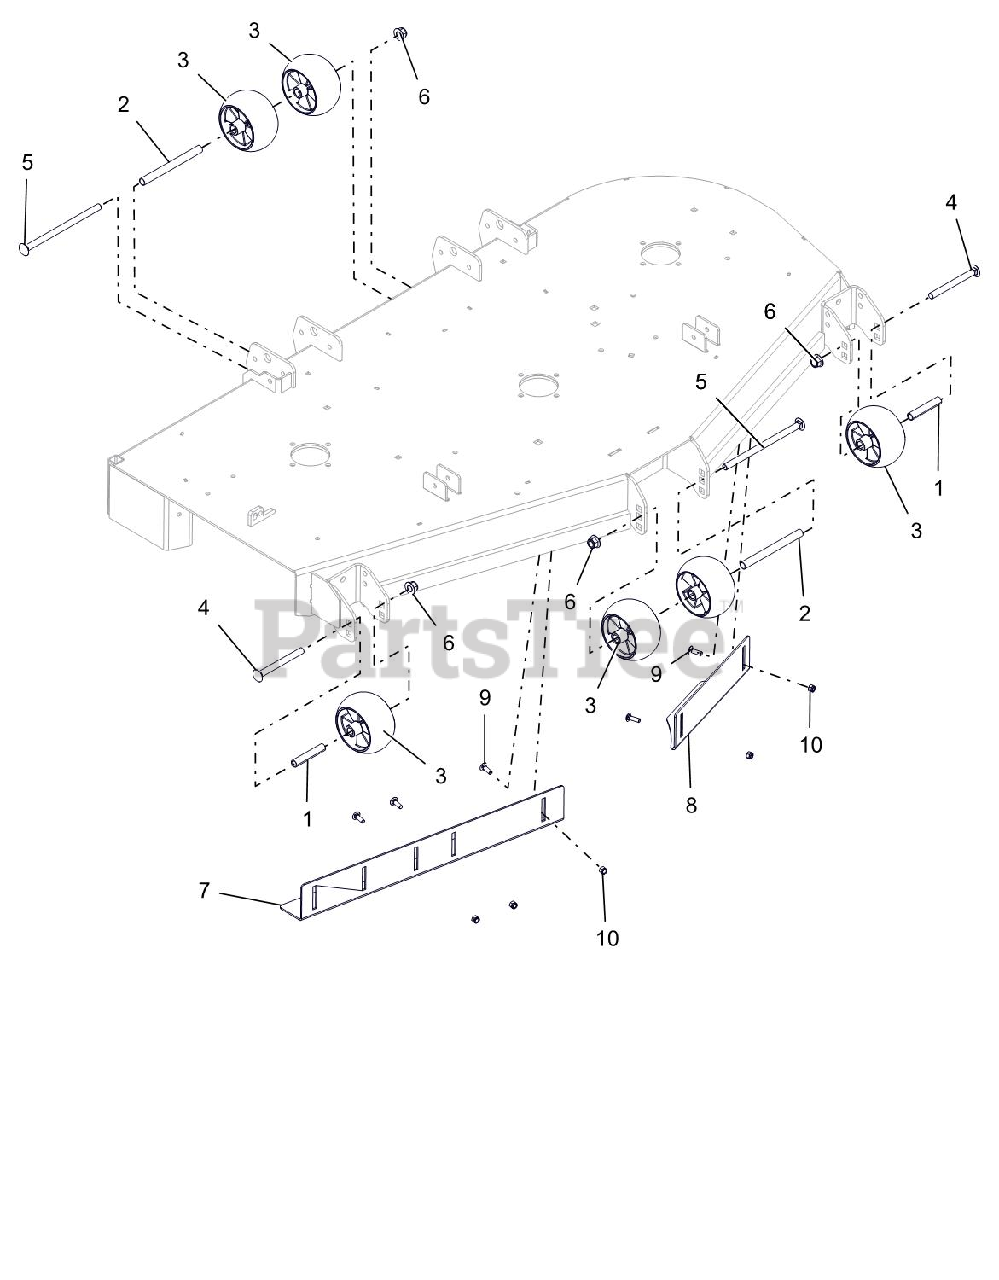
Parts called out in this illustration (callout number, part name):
1	SPACER, .510X.625X3.35
2	SPACER, .510X.625X6.50
3	ANTI-SCALP WHEEL - 5X3 CTR
4	BLT-RDHDSQNK .50-13X5.00 GR5YZ
5	@BLT-RDHDSQNK .50-13X8.50 G5YZ
6	@NUT-LK-NYL-FLG .50-13 YWZC
7	60" RH VACUUM BAFFLE - BLK
8	60" LH VACUUM BAFFLE - BLK
9	@BLT-RDHDSQNK .31-18X1.00 G5YZ
10	@NUT-LK-NYL .312-18 YWZC
